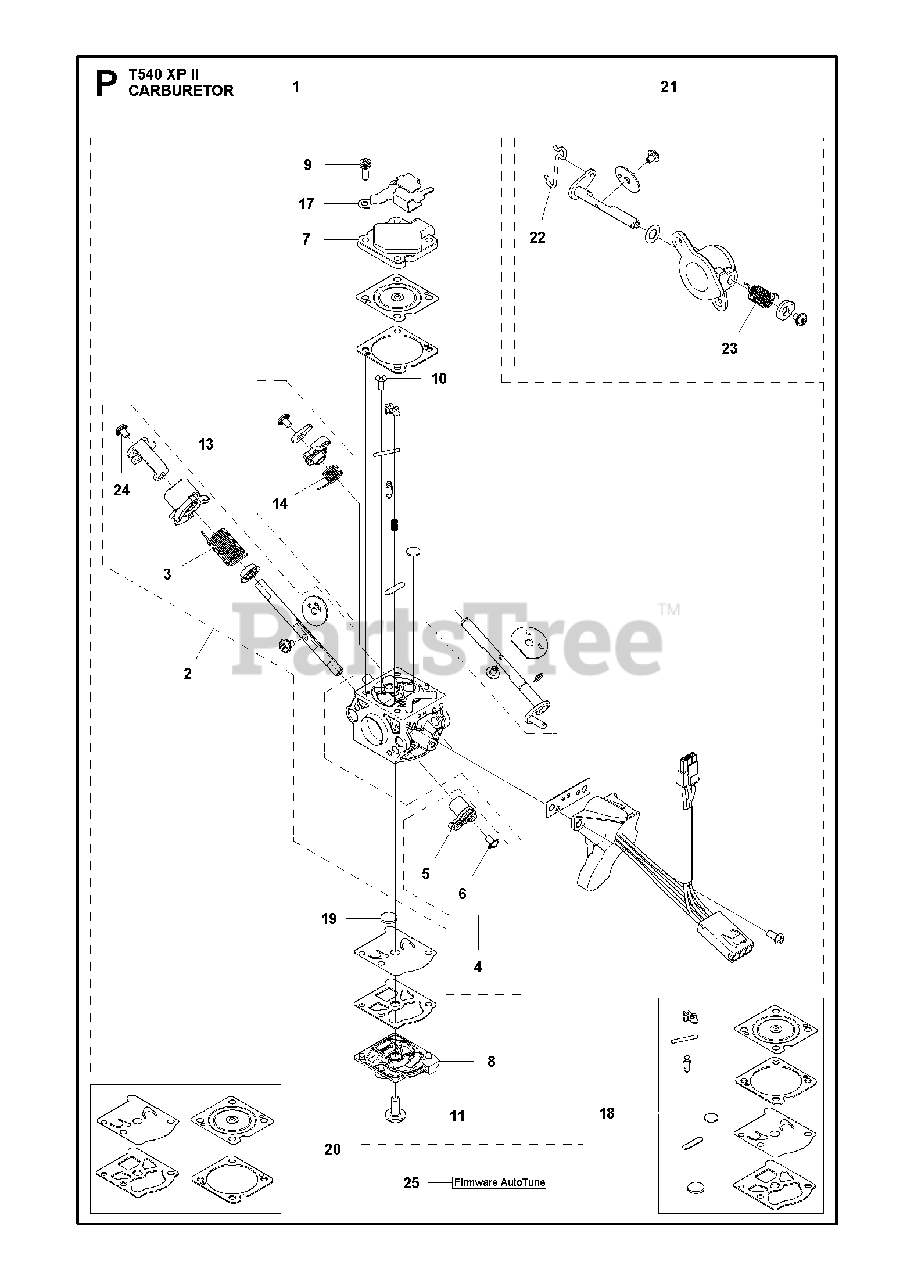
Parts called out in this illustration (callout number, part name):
1	CARBURETTOR ASSY
2	KIT
3	SPRING
4	THROTTLE LEVER ASSY
5	THROTTLE LEVER ASSY
6	SCREW
7	COVER
8	PUMP COVER
9	SCREW
10	SCREW
11	SCREW
13	KIT
14	SPRING
17	BRACKET CONTACT
18	REPAIR KIT
19	FUEL INLET SCREEN
20	GASKET KIT
21	THROTTLE ASSY
22	LINK
23	SPRING
24	SCREW
25	Husqvarna TBD
